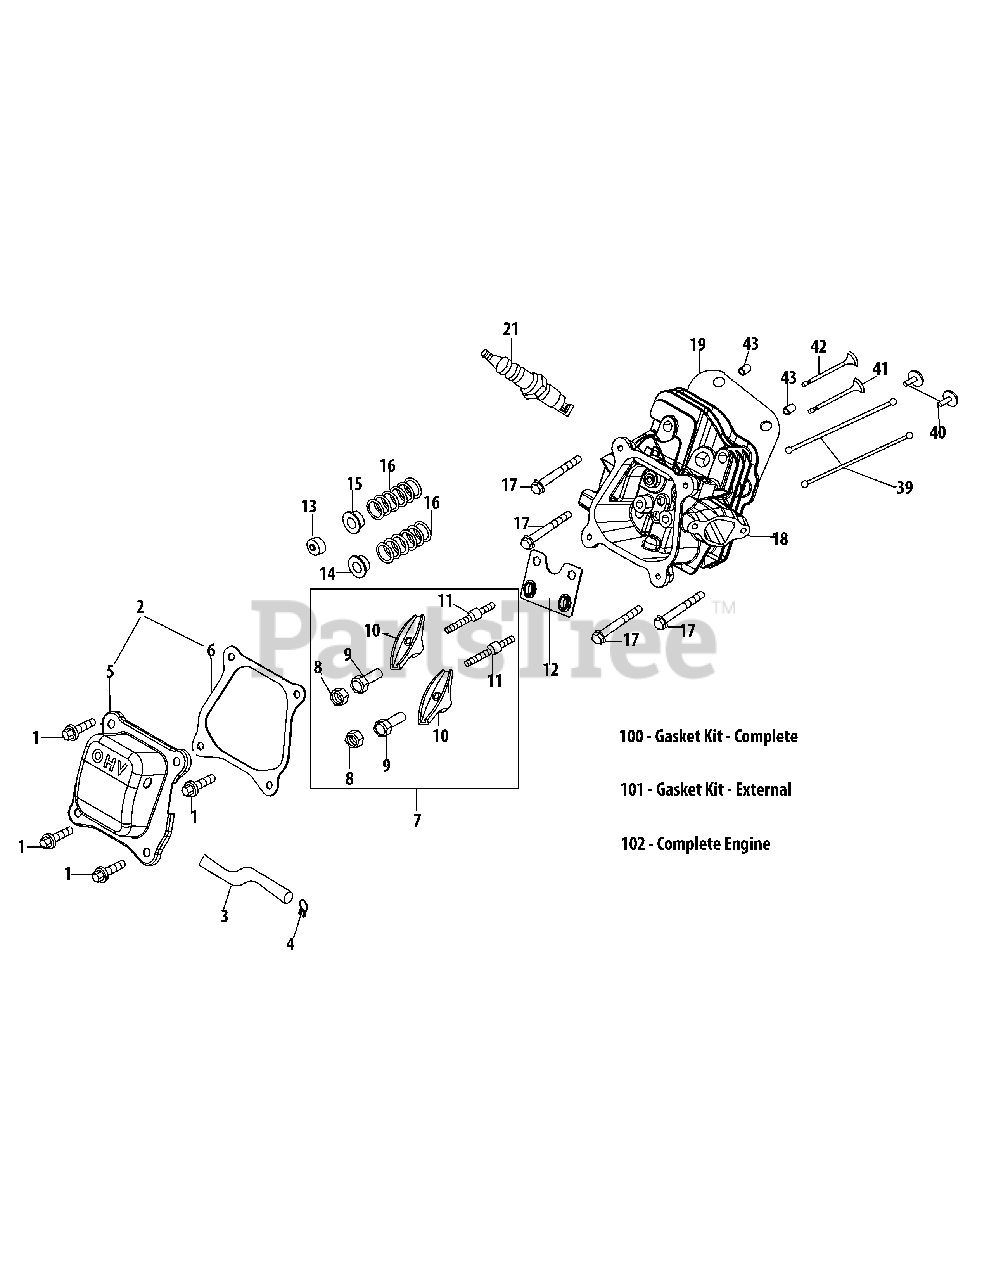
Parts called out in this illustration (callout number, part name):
1	Bolt m6×16
2	Valve Cover Kit
3	Breather Hose
4	Breather Hose Clamp
5	Valve Cover
6	Valve Cover Gasket
7	Rocker Arm Assembly
8	Nut, Pivot Lock
9	Adjusting Nut ,Valve
10	Rocker Arm
11	Bolt, Pivot
12	Plate, Push Rod Guide
13	Exhaust Lash Cap
14	Valve Spring Retainer (Intake)
15	Valve Spring Retainer (Exhaust)
16	Valve Spring
17	Bolt, Flange, 8×50
18	Cylinder Head Assembly
19	Gasket, Cylinder Head
21	Spark Plug/F6Rtc
39	Push Rod Kit
40	Tappet
41	Valve Kit
42	Valve Kit
43	Pin, Dowel, 10×16
100	Gasket Kit - Complete
101	Gasket Kit - External
102	Complete Engine
